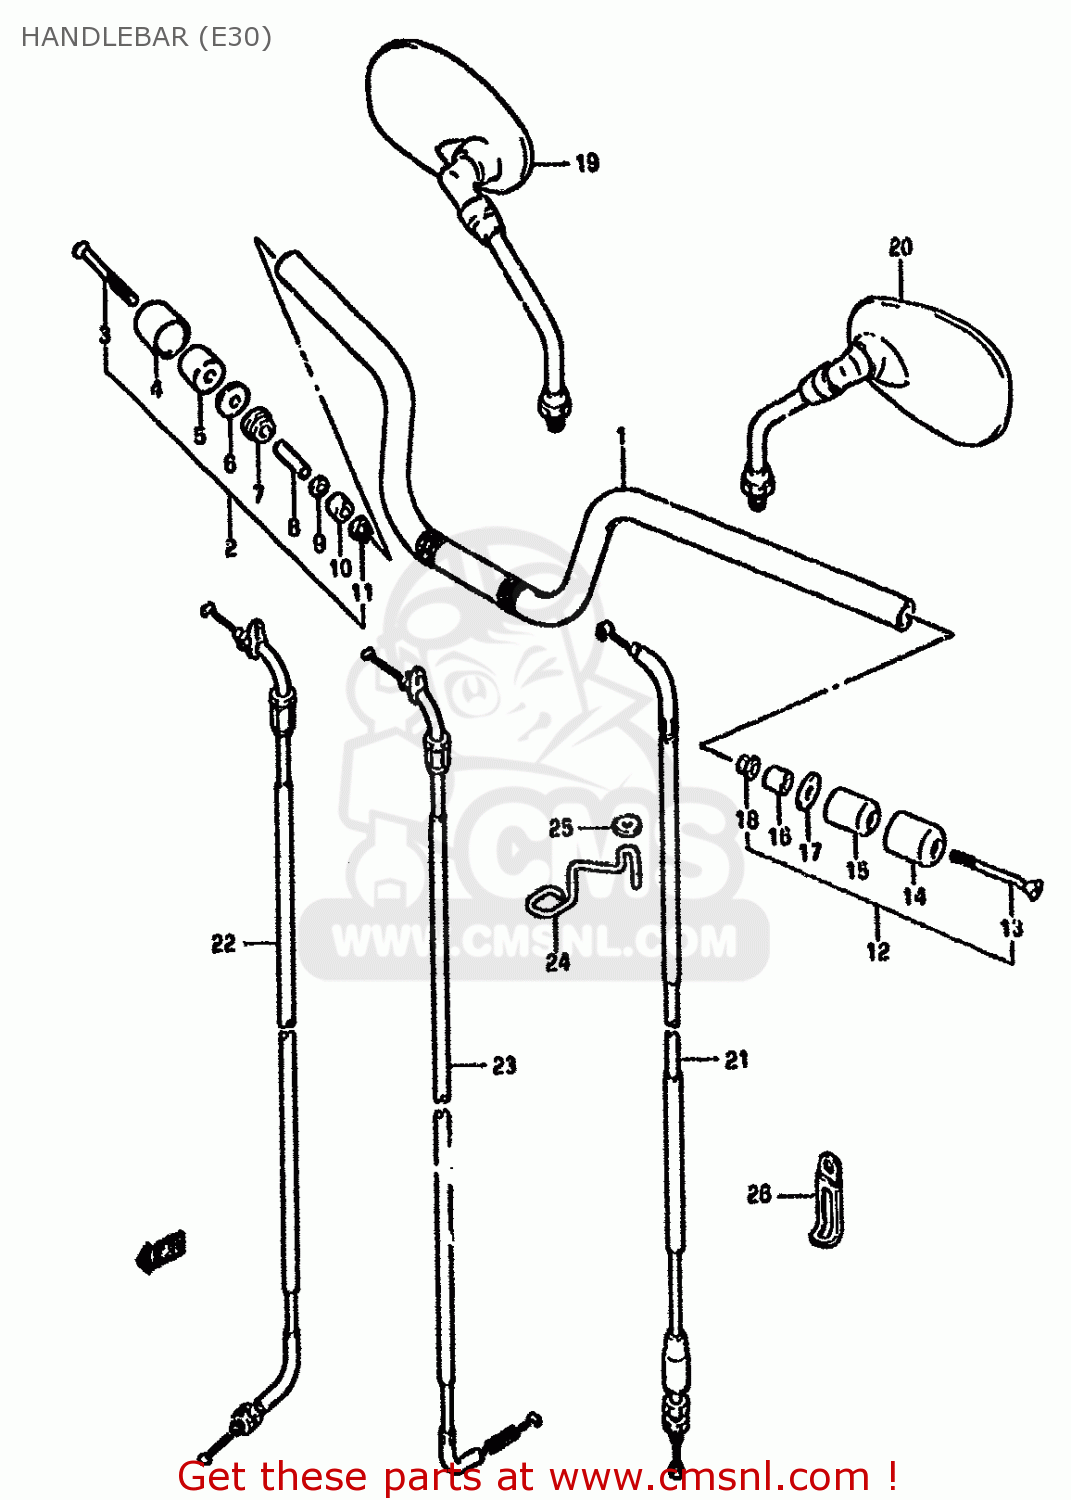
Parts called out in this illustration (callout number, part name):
1	HANDLEBAR,RIGHT
2	BALANCER SET,HANDLEBAR
3	SCREW(6X127)
4	CAP,BALANCER
5	BALANCER,HANDLEBAR
6	SPACER,BALANCER
7	EXPANDER,HANDLE BALANCER
8	SPACER,EXPANDER
9	WASHER
10	EXPANDER,HANDLE BALANCER
11	NUT
12	BALANCER SET,HANDLEBAR
13	SCREW
14	CAP,BALANCER
15	BALANCER,HANDLE
16	EXPANDER,HANDLE BALANCER
17	SPACER,BALANCER
18	NUT
19	MIRROR ASSEMBLY,REAR VIEW
20	MIRROR ASSEMBLY,REAR VIEW
21	CABLE ASSY,CLUTCH
22	CABLE ASSY,THROTTLE
23	CABLE,STARTER
24	GUIDE,CLUTCH CABLE
25	WASHER (6.5X20X1.6)
26	CLAMP
